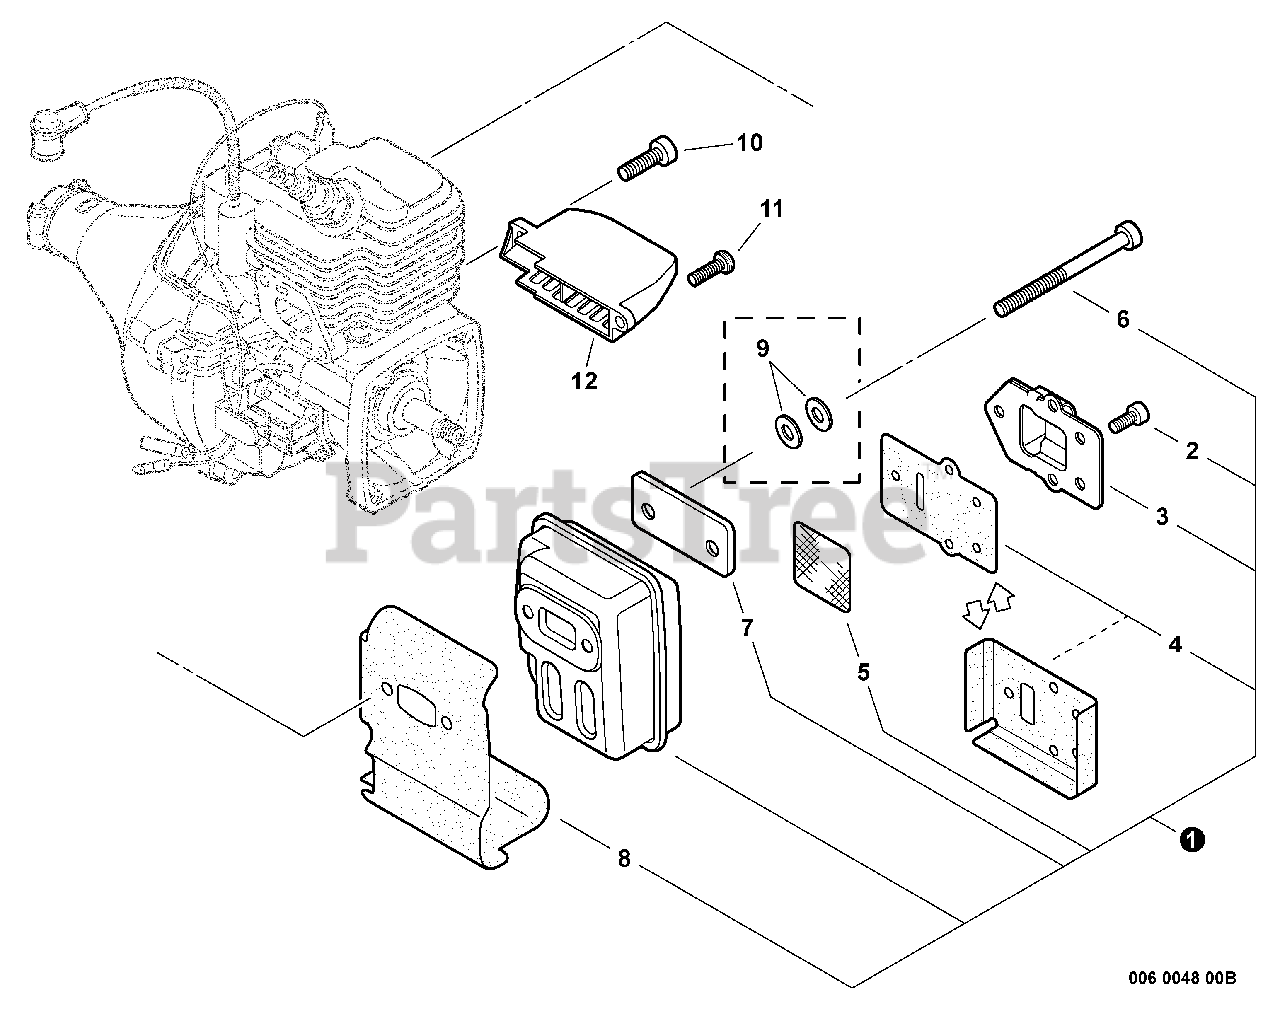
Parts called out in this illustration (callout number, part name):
1	MUFFLER ASSY
2	BOLT, TORX 4×8
3	GUIDE, EXHAUST
4	GASKET, EXHAUST
5	SCREEN, SPARK ARRESTER
6	BOLT, TORX 5×55
7	PLATE, EYE
8	HEAT SHIELD, EXHAUST
10	BOLT, TORX 5×16
11	BOLT, TORX 5×16
12	COVER, MUFFLER
